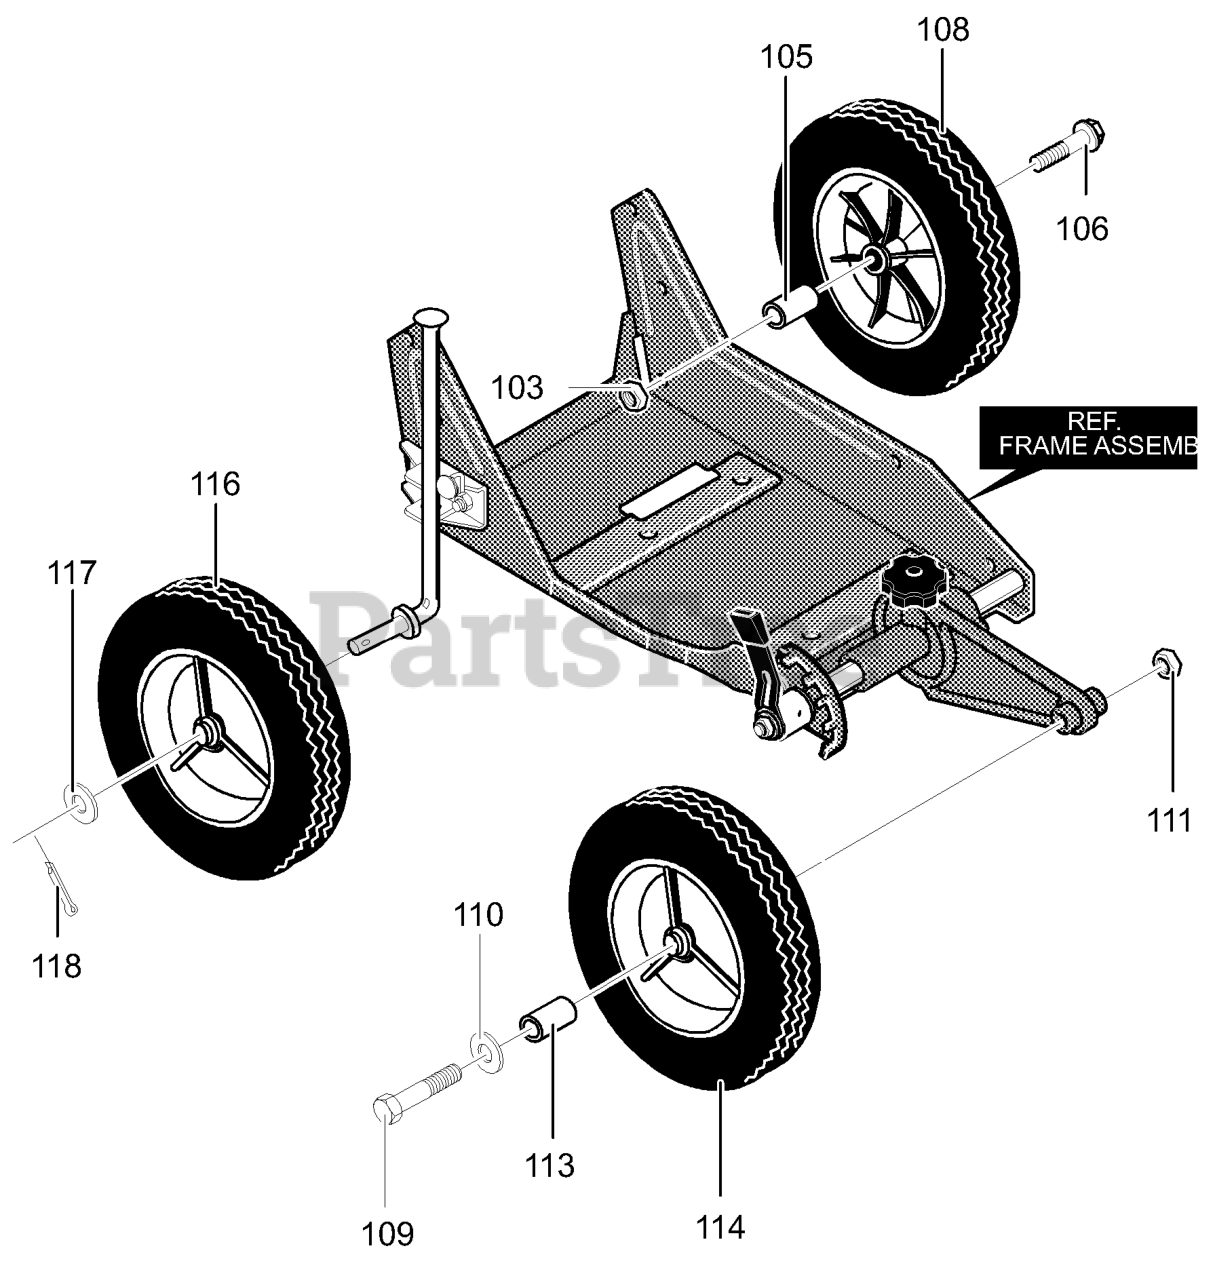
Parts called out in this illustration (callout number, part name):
103	Nut, 3/8-16 Reghexctrlk
105	Spacer, Sleeve
106	Bolt, HHSH 3/8
108	Tire & Rim
109	Screw, 5/16-18 x 3.00
110	Flatwasher
111	Nut, 5/16-18 Wdfllk
113	Spacer, Sleeve
114	Tire & Rim
116	Tire & Rim
117	Flatwasher
118	Cotter Pin
